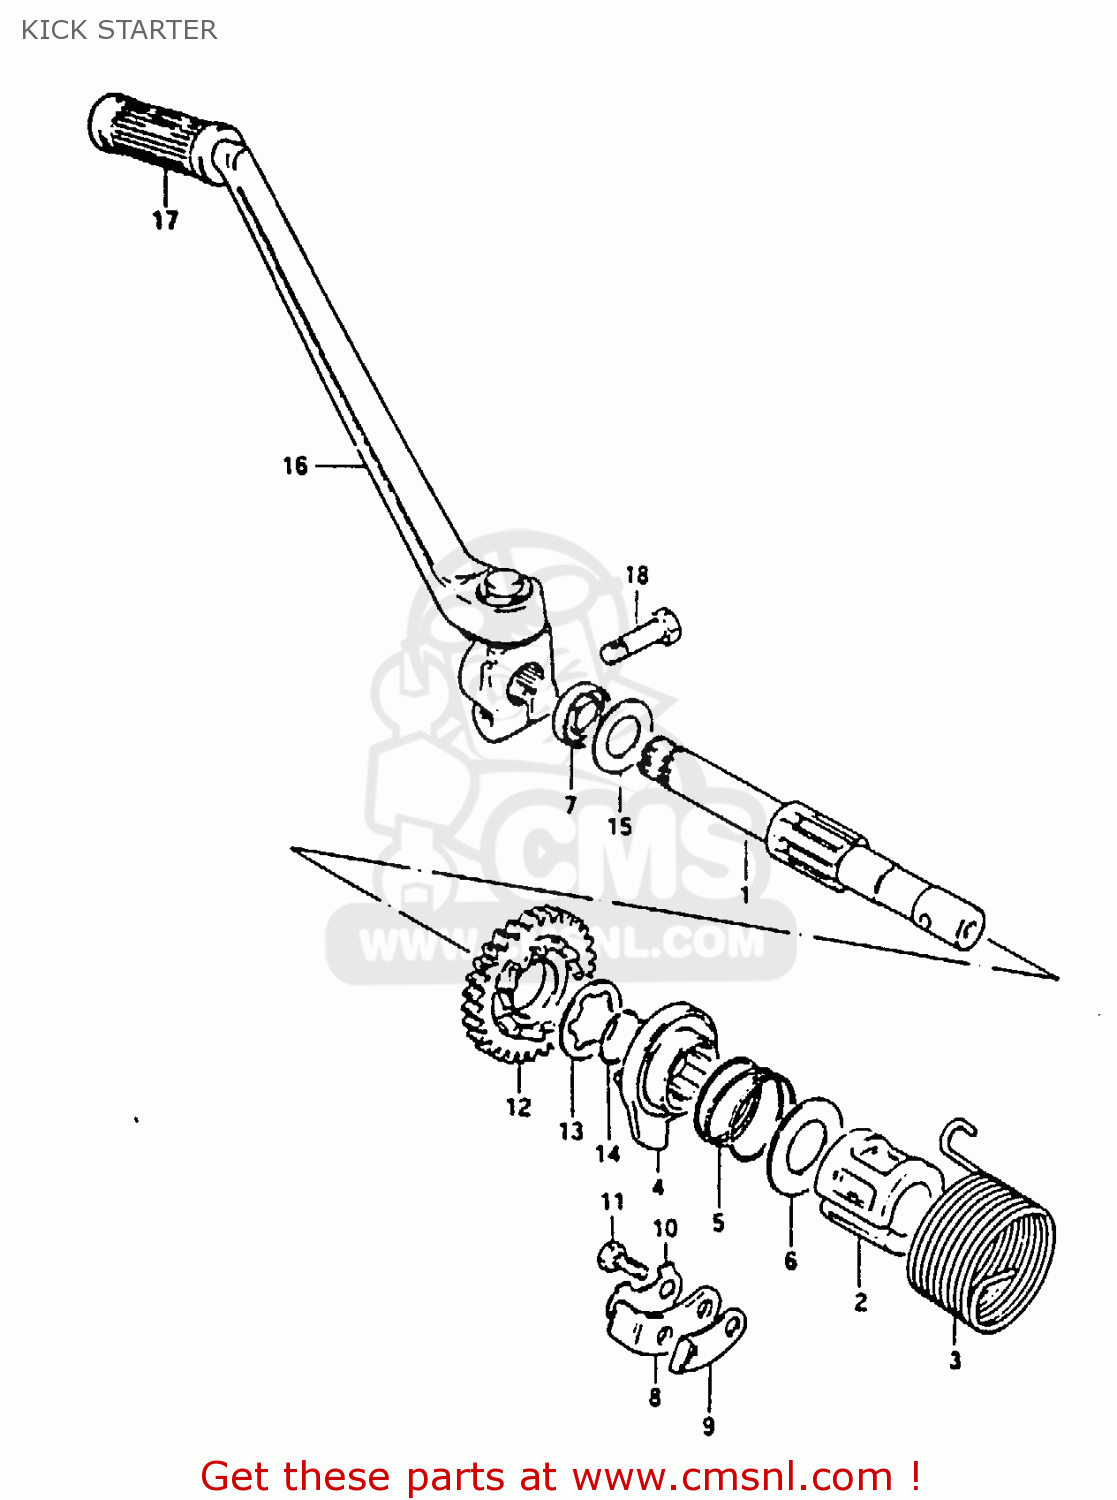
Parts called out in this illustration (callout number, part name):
1	SHAFT,KICK STARTER
2	GUIDE,KICK STARTER SFT SPRING
3	SPRING
4	STARTER,KICK
5	SPRING
6	WASHER
7	SEAL,OIL(16X30X8)
8	GUIDE,KICK STARTER
9	STOPPER,KICK STARTER
10	WASHER
11	BOLT
12	GEAR,KICK STARTER DRIVE
13	WASHER,LOCK
14	CIRCLIP
15	WASHER(16X30X1)
16	LEVER ASSY, KICK STARTER
17	RUBBER,KICK STARTER PEDAL
18	BOLT
